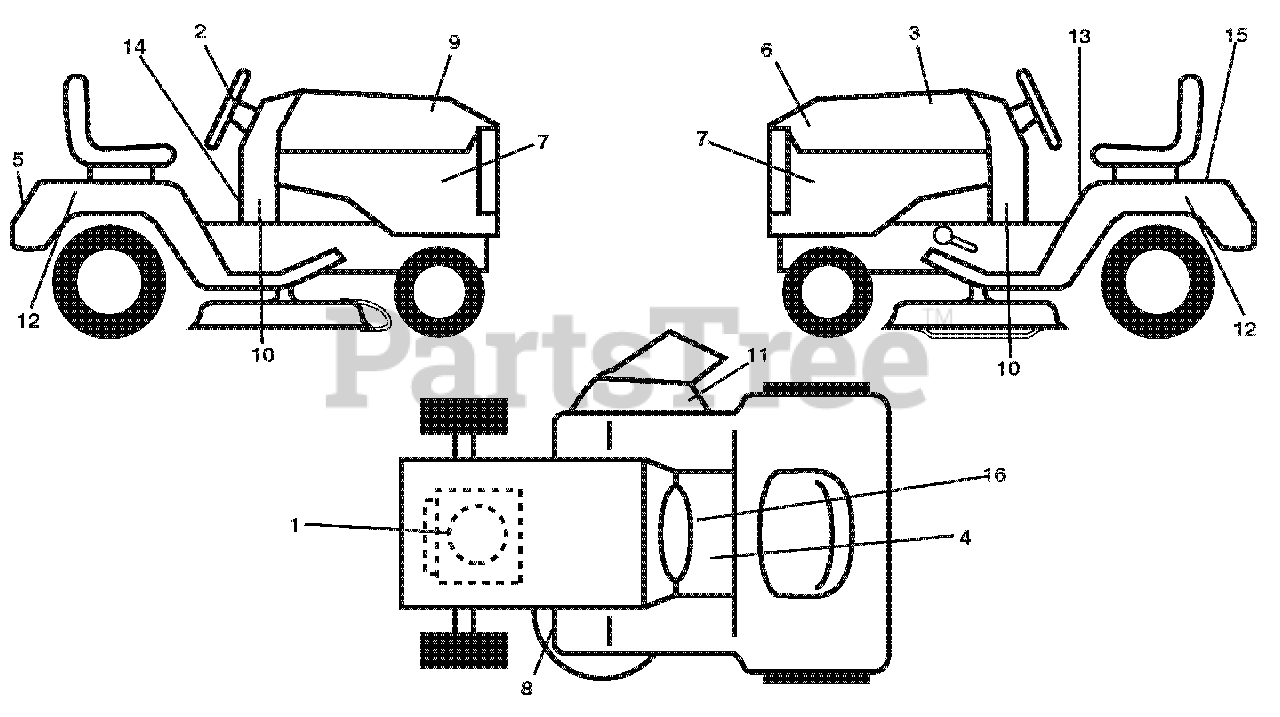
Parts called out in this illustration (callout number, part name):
1	DECAL, REPLACEMENT
2	Decal, Ins Str Wh
3	DECAL.REPLACEMENT
4	DECAL.FENDER
5	DECAL.FENDER.REAR.ARIENS
6	DECAL.HOOD.LH
7	DECAL.SDPNL.PWRDBY B&S.ARIENS
8	DECAL.V-BELT.SCH.
9	DECAL.HOOD.RH
10	DECAL, DASH LOWER
11	DECAL.WARNING.KEEP.HAND.AWY
12	DECAL.FENDER.SD.GEAR.DR
13	Decal, Spark Arrester
14	DECAL.WARNING.START
15	DECAL.BAT.DAN/POI P/L SYM.WPN
16	LABEL.EMISSIONS
